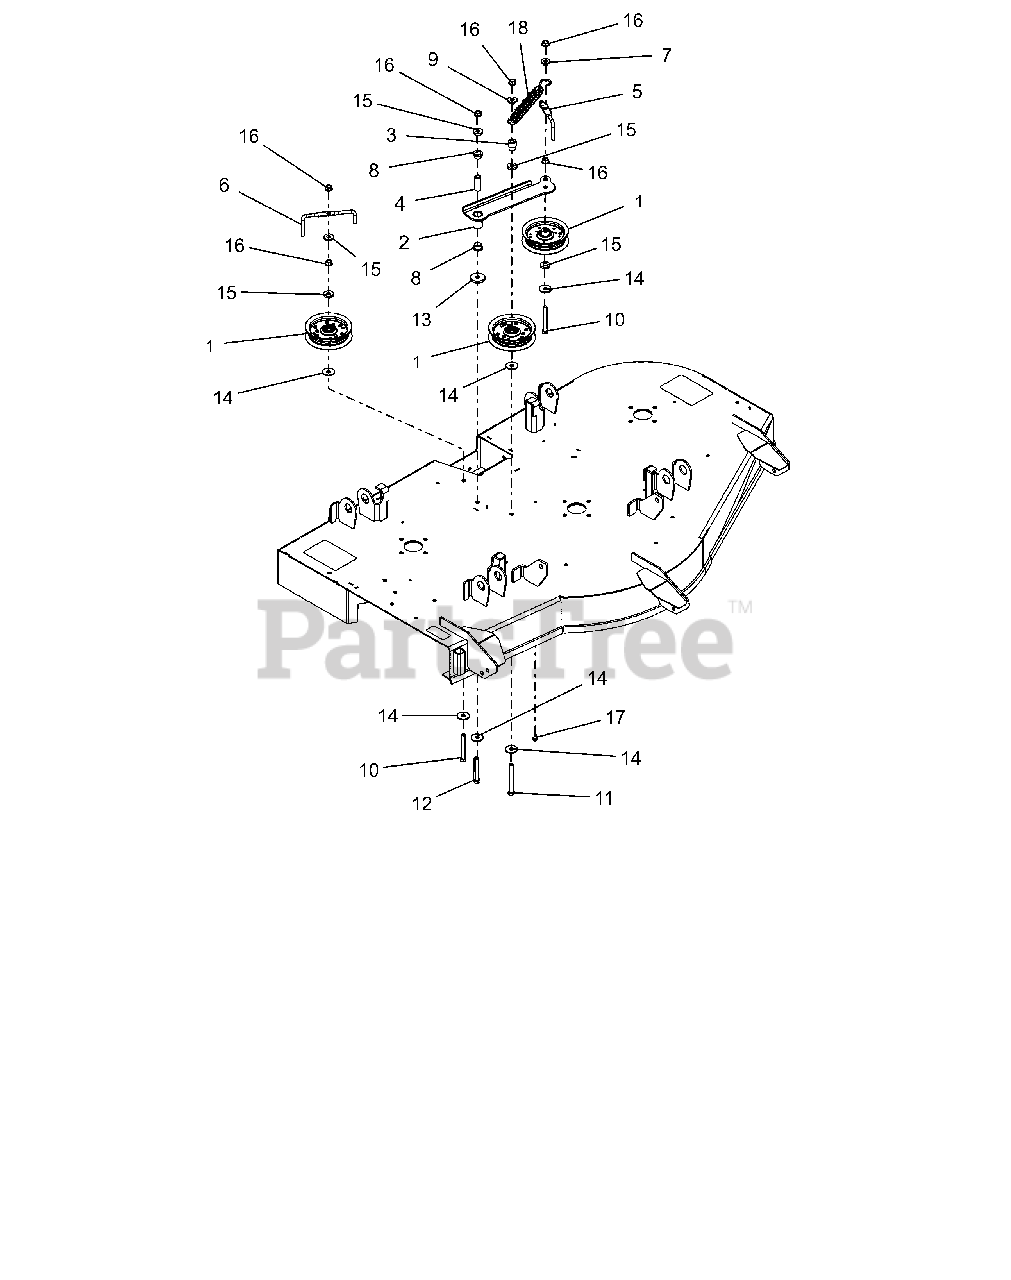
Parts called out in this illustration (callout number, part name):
1	ASM, IDLER 4"
2	WLDMT, IDLER ARM-52"
3	BUSHING, IDLER (P/M)
4	SPACER, .375IDX.625ODX1.66 PM
5	WIREFORM, BELT FINGER
6	WIREFORM, BELT FINGER
7	BSHG-FLG .385X.500X.875X.406
8	BSHG-FLG, .625X.750X.500X1.00
9	BSHG-FLG .385X.500X.875X.31
10	BLT-HEX .38-16X3.00 GR5 FTH YZ
11	@BLT-HEX .38-16X3.50 GR5 YWZC
12	@BLT-HEX .38-16X2.75 GR5 YWZC
13	WSHR,FLT STL.406X1.50X.245YWZC
14	WSHR-FL-STL .406X1.25X.10 ZC
15	WSHR-FL-STL .406X1.00X.188 YWZ
16	@NUT-LK-TOP-FLG .38-16 YWZC
17	SCR-TAP .25-20X.50 HWH TR YWZ
18	SG-TENS .135X.98X6.0 WLD 62
